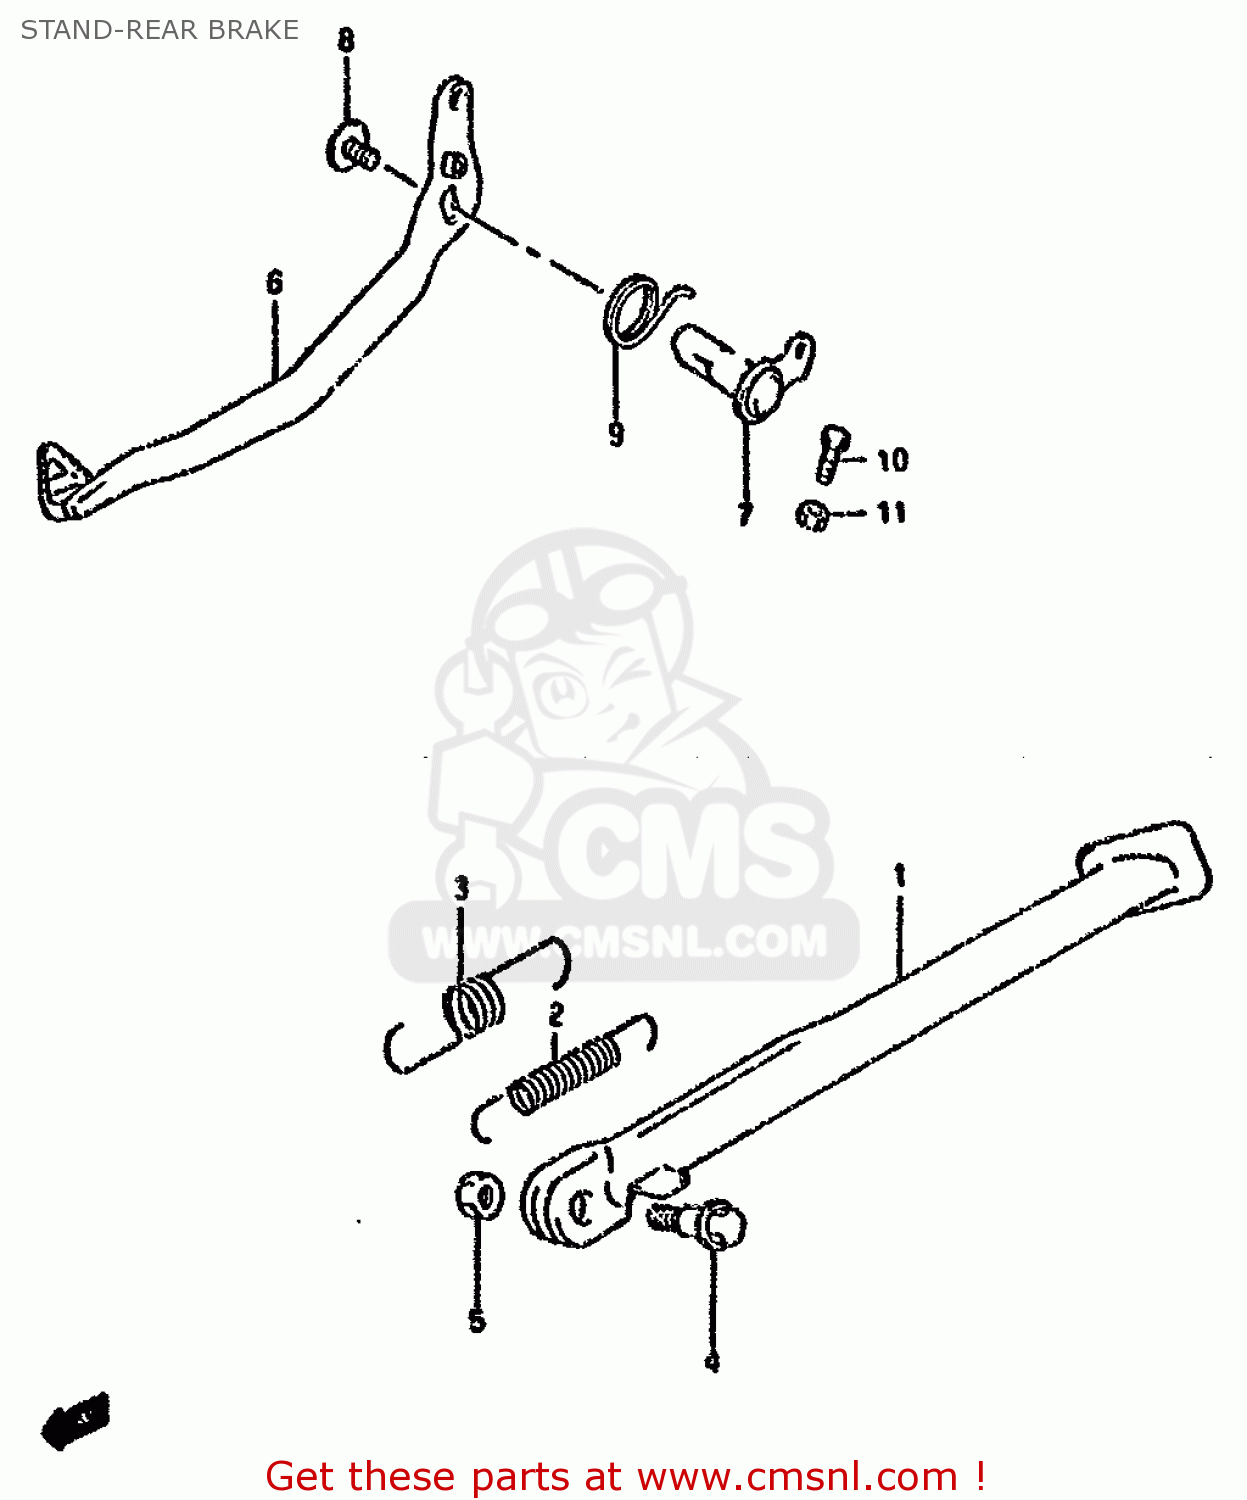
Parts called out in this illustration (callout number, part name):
1	STAND, PROP (BLACK)
2	SPRING
3	SPRING
4	BOLT(10X33.5)
5	NUT
6	PEDAL,BRAKE
7	ARM,BRAKE PEDAL ROD
8	BOLT(8X14)
9	SPRING
10	BOLT(6X23)
11	NUT
